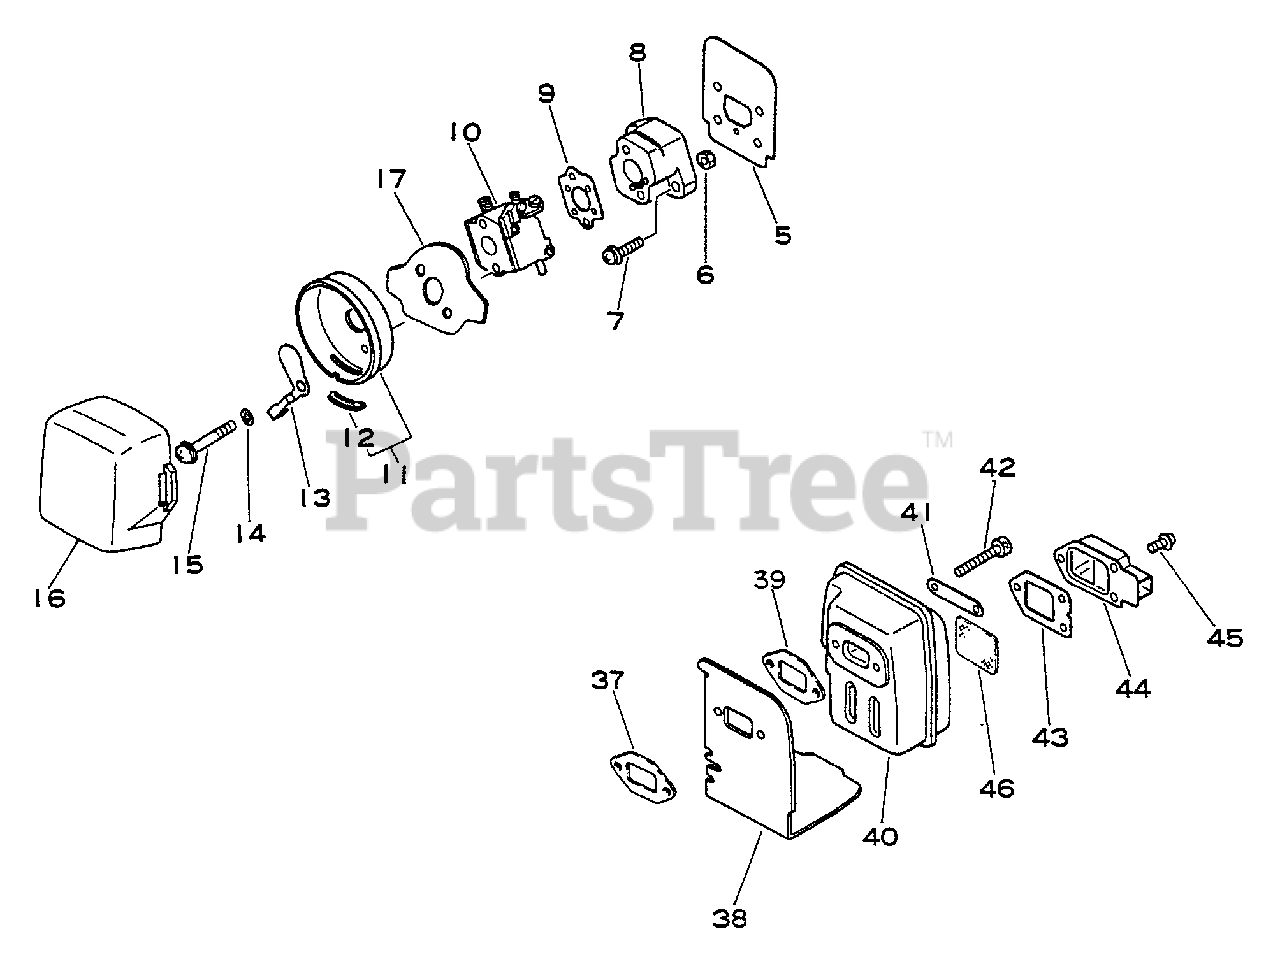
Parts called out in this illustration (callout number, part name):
5	SHIELD, INTAKE
7	SCREW - 5X20
8	INSULATOR, INTAKE
9	GASKET, INTAKE
10	CARBURETOR C1U-K4
11	CASE, AIR FILTER
12	GROMMET
13	SHUTTER, CHOKE
14	WASHER - 5
15	SCREW - 5X55
16	FILTER, AIR
17	GASKET, INTAKE
37	GASKET, EXHAUST
38	COVER, MUFFLER
39	GASKET
42	SCREW - 5X55
43	GASKET, EXHAUST
44	GUIDE, EXHAUST - OUTER
45	SCREW - 4X10
46	SCREEN, SPARK ARRESTOR
